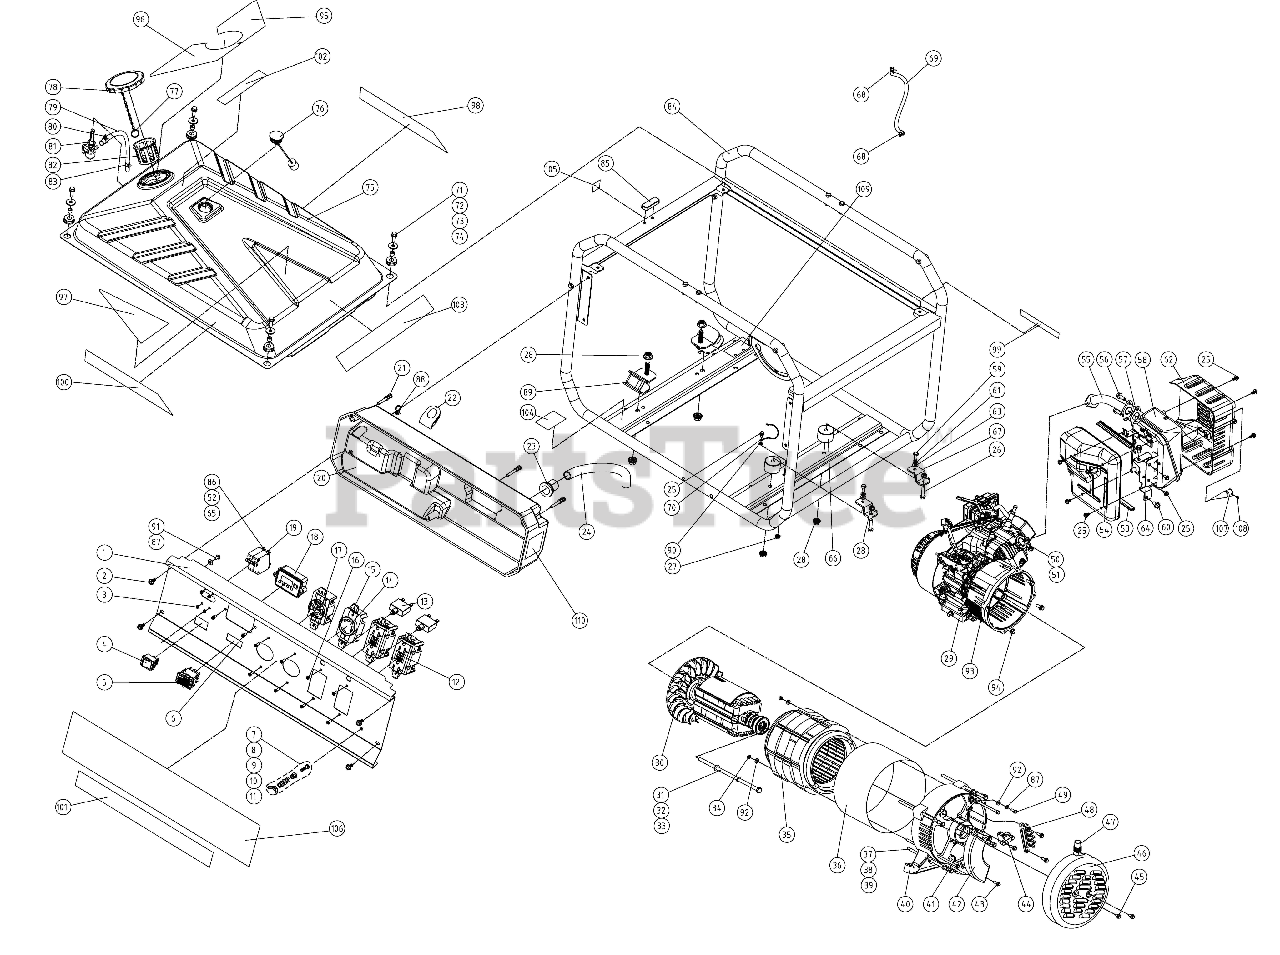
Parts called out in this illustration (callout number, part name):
1	Panel (PRO3.7)
2	SCREW, BOLT GB5789-M6X12
3	SCREW, M3X6
6	SCREW M4X12
8	SCREW, BOLT M6X25
10	WASHER, PLATE GASKET 6
11	WASHER, SPRING GASKET 6
12	RECEPTACLE, GFCI 20A/125V NEMA 5-20OR
13	BREAKER, CIRCUIT 20A
14	RECEPTACLE, NEMA L5-30R SOCKET
15	PLATE NUT
17	RECEPTACLE, NEMA L14-30R 4P SOCKET
18	DIGITAL DISPLAY METER
19	CIRCUIT BREAKER
20	PANEL BOX PRO3.7E
21	SCREW M5X45
22	WIRE SHEATH
23	GROMMET, POWER CORD SHEATH
24	SLEEVE BRAIDED SLEEVE 1
25	SCREW, BOLT M6X12
26	BOLT M8X40 GB 5789
30	ROTOR ASSEMBLY
31	BOLT 5/16-24X231 MM
33	WASHER, SPRING
35	STATOR ASSEMBLY
36	STATOR PROTECTOR
37	WASHER, SPECIAL SPRING 6
38	WASHER, PLATE GASKET 6
39	SCREW BOLT M6X180
40	CAP, BACK COVER
41	BOLT M5X715
42	RECTIFIER AVR (PRO5.5E)
43	SCREW, BOLT GB 5787-M5X16
44	BRUSH, CARBON ASSEMBLY
45	SCREW, BOLT M5X10
46	FAN COVER
47	SLEEVE, MOTOR RUBBER SHEATH
48	BOARD ASSEMBLY, PATCH
49	BOLT GB/T 5783-M5X10
52	WASHER, SPRING GB93-4
53	RUBBER GASKET
54	MUFFLER BACK COVER
55	MUFFLER PIPE WELDING ASSEMBLY
56	SCREW, BOLT M8X22
58	MUFFLER WELDING ASSEMBLY
59	BOLT M8X16
60	SCREW, BOLT M8X16
61	WASHER, SPRING 8
62	MUFFLER FRONT COVER
63	WASHER, FLAT GASKET 8
64	MUFFLER BRACKET PRO 3.7
66	RUBBER FOOT
67	ADAPTER BRACKET
68	CLAMP, FUEL PIPE 5
69	FUEL LINE
70	GROUND WIRE
71	SCREW, BOLT GB 5787-M6X20
72	MOUNT, FLAT GASKET GB/T 5287-6
73	SPACER, INNER RING
74	SPACER, FUEL TANK BUSHING
75	TANK ASSEMBLY (PRO3.7E)
76	FUEL LEVEL GAUGE ASSEMBLY
77	RETAINER, TANK CAP PULL RING
78	CAP ASSEMBLY - FUEL TANK (EPA)
79	FUEL LINE
80	CLAMP, FUEL LINE 6
81	VALVE,FUEL SHUT OFF
82	FILTER , FUEL TANK
83	CLAMP, FUEL LINE 1 USE 14 237 01-S
84	FRAME ASSEMBLY
85	DAMPER, HANDLE DAMPING PAD
86	SCREW GB818-M4X8
87	WASHER, SPRING GB 93-5
88	STRAP, CABLE TIES 3.2X120 (WHITE)
89	VIBRATION ABSORBER
90	GROOVED METAL GASKET 6
91	SCREW M5X12
92	WASHER, PLATE GT/T 95
93	FRONT COVER
94	BOLT 5/16-24 27MM
95	LOGO LABEL (RESERVOIR PORT)
96	WARNING LABEL
97	RUNNING WATTS LABEL
98	LEFT LOGO LABEL (FUEL TANK)
99	SAFETY DECAL
100	CPSC DECAL_5.2
101	QUICK START LABEL
102	DECAL, OSHA
103	DECAL, GENERATOR_WARNING
105	FUEL SWITCH DECAL
106	PANEL LABEL
107	SPARK ARRESTER
109	PERFORMANCE DECAL
110	(CSA) EMC DECAL
